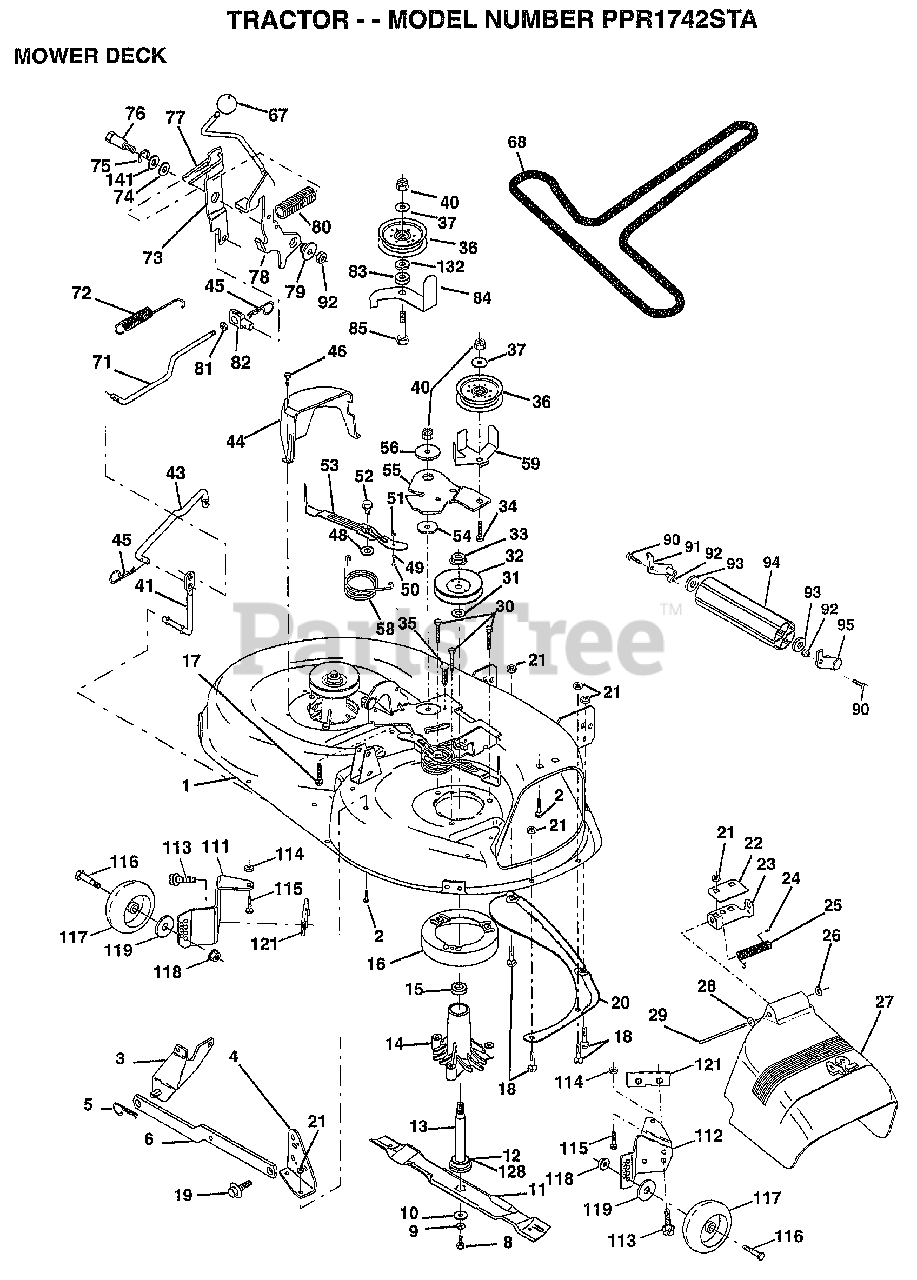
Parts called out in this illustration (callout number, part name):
1	"HOUSING ASSY.42"""
2	BOLT
3	BRKT ASM SWAY BAR
4	BRKT DECK SW BAR
8	BLADE BOLT
10	WASHER.HARD.BLADE
11	"BLADE.42"" HIPERF"
12	BEARING.BALL
14	HSG ASM MANDREL
15	BEARING
16	STRIPPER RND MWR
17	BOLT RDHD 3/8-16
18	BOLT
19	BOLT SHD 5/16-18
20	BAFFLE VORTEX 42
22	STIFFENER BRKT
23	DEFLECTOR BRKT
24	CAP-SLEEVE LT
25	SPRING TORSION
26	NUT PUSH M
27	DEFLECTOR.SHIELD
28	WASHER
29	HINGE ROD
30	"SCREW-THD ROLL,WA"
31	WASHER
32	PULLEY.MANDREL.42
34	BOLT
35	XMAS TREE FASTNER
36	FLAT IDLER PULLEY
37	WASHER
41	PIVOT ROD
43	ROD CLUTCH W/NIBS
44	GUARD MAND LH BLK
45	RETAINER M
46	SCREW.1/4-20X5/8
48	HARD SMALL WASHER
49	ROLLER ASM-CAM
50	SHOULDER BOLT
51	LOCKNUT
52	BOLT.SHLD.5/16-18
53	BRAKE PAD ARM ASM
54	HARDENED WASHER
55	ARM-IDLER
56	SPACER RETAINER
58	SPRING TORSN BRAK
59	GUARD IDLER TUV
67	KNOB.RD.7/16-14
68	BELT.V.T-PATH
71	ROD CLUTCH 38/42
72	RETURN SPRING
73	CLUTCH ARM SECOND
74	WASHER
75	RING
76	SHOULDER BOLT
77	SPRING KEEPER
78	LEVER.ASM.CLUTCH
79	BUSHING
80	SPRING.CLUTCH.MWR
81	NUT
82	TRUNION ADJ
83	WASHER
84	"KEEPER-BELT,FIXED"
85	BOLT
90	BOLT
92	NUT
93	WASHER
111	BRACKET.GWHL.LH.
112	BRACKET.GWHL.RH.
113	SCREW
116	BOLT M
117	WHEEL.GUAGE
118	LOCKNUT
119	WASHER
121	BRACKET.EXTRD.GWL
128	WASHER.FELT.
132	WASHER GT
141	WASHER .T
